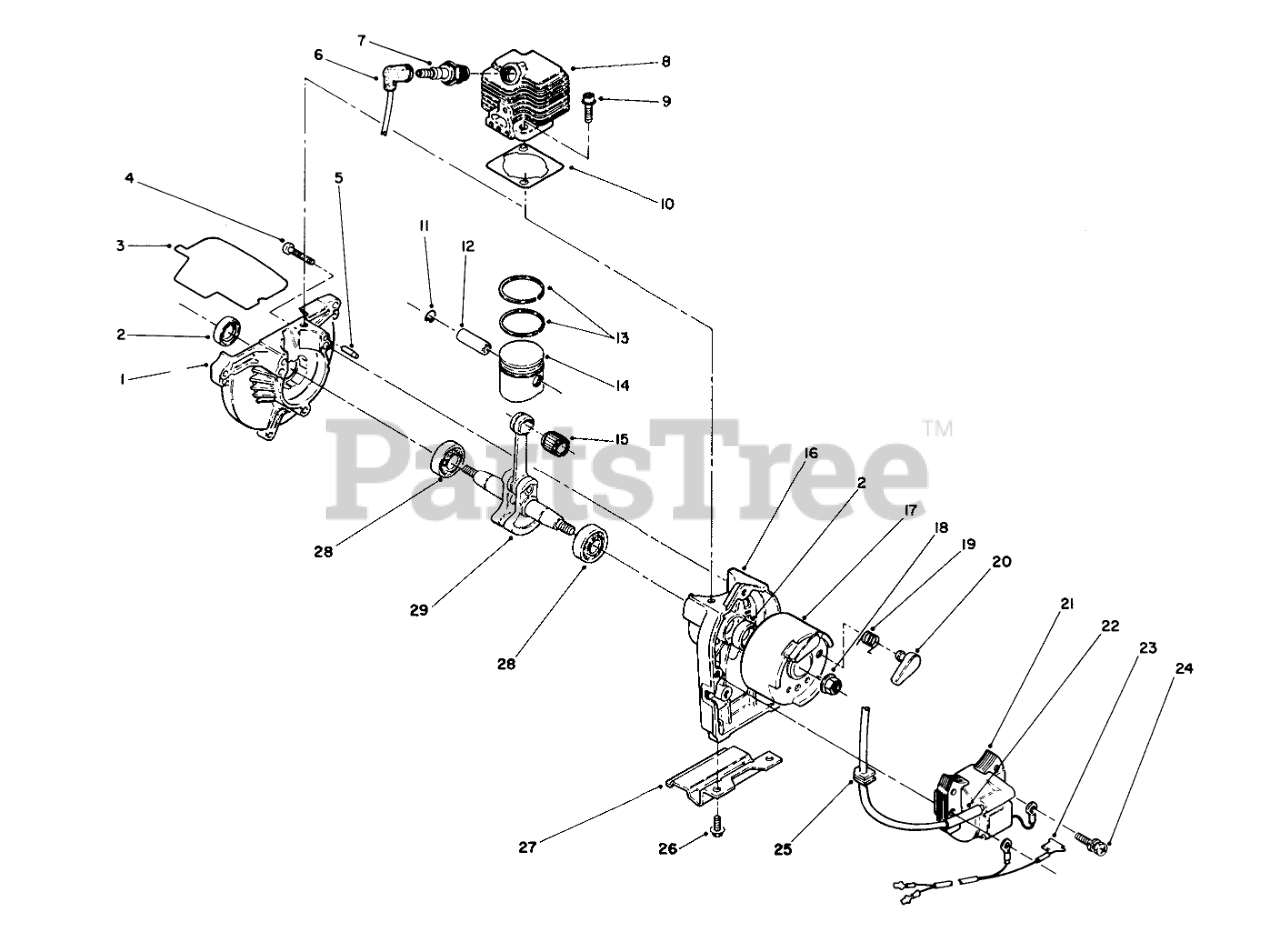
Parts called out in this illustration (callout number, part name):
1	Case-Drive
2	OIL SEAL
3	Gasket-Baffle
4	Screw
6	PLUG BOOT
7	Plug-Spark
8	CYLINDER
9	FLANGE BOLT
10	CYL GASKET
11	PISTON PIN CLIP
12	PISTON PIN
13	TOP RING
14	Piston (Incl. Ref. #12)
15	NEEDLE BEARING
16	STARTER CASE
17	Flywheel (Incl. Ref. #19 & 20)
19	RETURN SPRING
20	RATCHET
21	IGNITION COIL
23	LEAD WIRE
24	BOLT AND WASHER
25	GROMMET
26	SCREW & WASHER
27	STAND
28	BEARING
29	CRANKSHAFT ASSEMBLY
